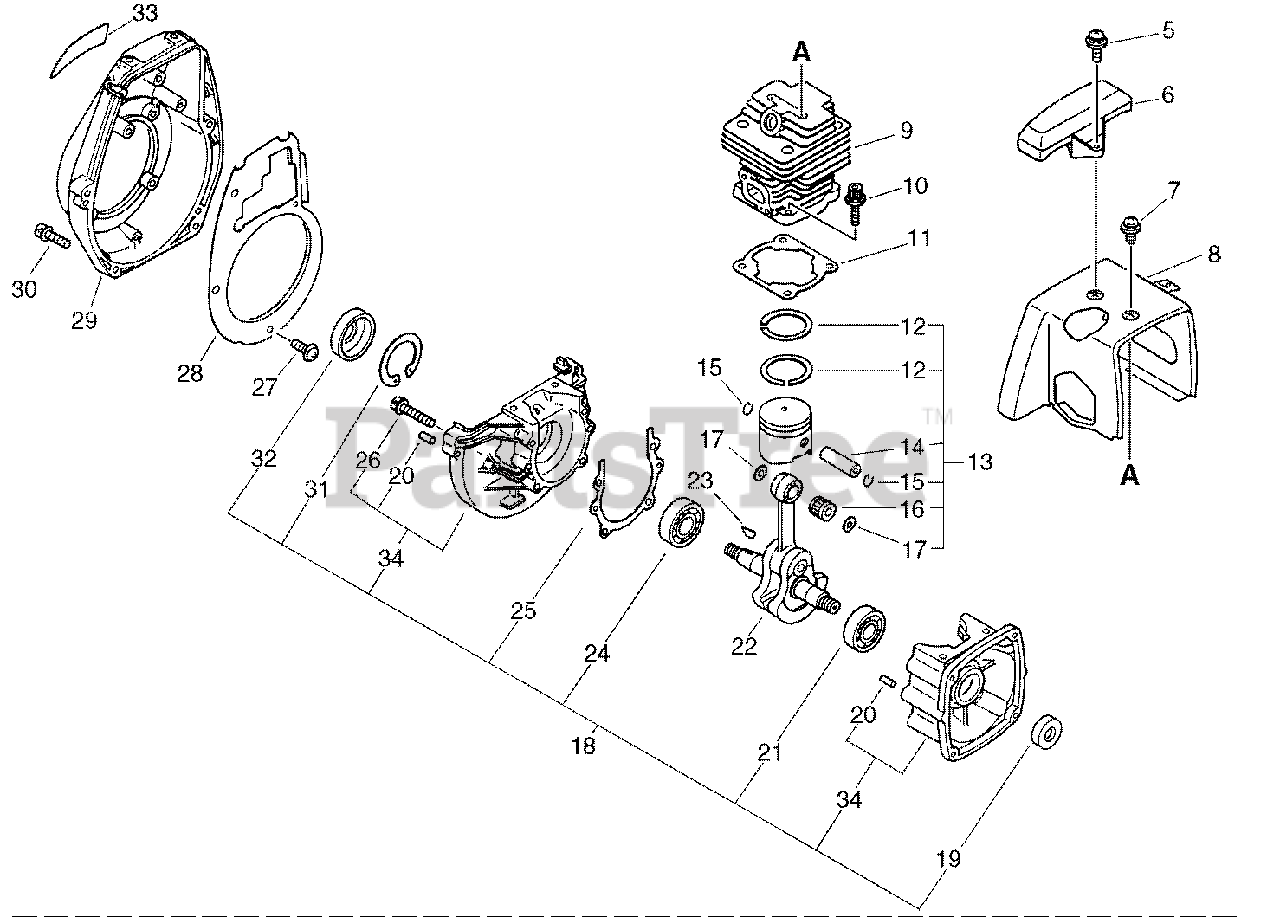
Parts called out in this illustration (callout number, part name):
5	SCREW 5×14
6	GUARD, TOP
7	SCREW 5×10
8	COVER, ENGINE
9	CYLINDER
10	BOLT 5×20
11	GASKET, CYLINDER
12	RING, PISTON
13	PISTON KIT
14	PIN, PISTON
15	RING, SNAP 8
16	BEARING, NEEDLE 10
17	WASHER, THRUST 10
18	CRANKCASE KIT
19	SEAL, OIL 12
20	PIN, LOCATING 5×10
21	BEARING, BALL - 6201 C3
22	CRANKSHAFT ASSY
23	KEY, WOODRUFF
24	BEARING, BALL 6203 C3
25	GASKET, CRANKCASE
26	BOLT 5×30
27	SCREW 4×10
28	GUIDE, AIR
29	COVER, FAN
30	BOLT 5×25
31	RING, SNAP 35
32	SEAL, OIL 18
33	LABEL - MODEL
34	CRANKCASE KIT
